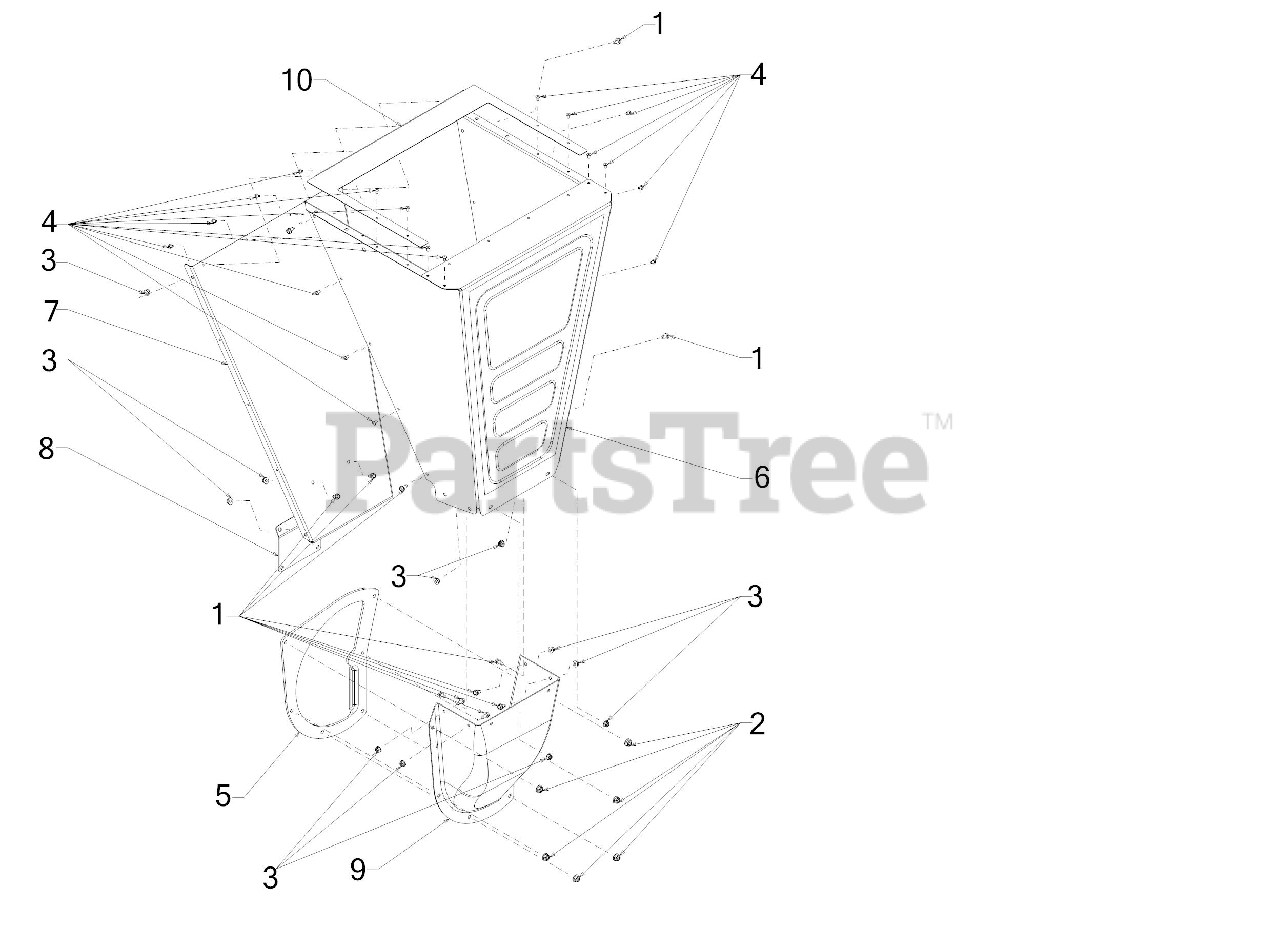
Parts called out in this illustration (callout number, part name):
1	SCREW 1/4-20 X.500
2	FLANGE LOCK NUT 5/16-18
3	FLANGE LOCK NUT
4	FULL TUBULAR RIVET
5	SHREDDER PLATE
6	HOPPER FRONT PANEL
7	HOPPER BACK PANEL
8	HOPPER BRACKET SUPPORT
10	HOPPER TOP PANEL
